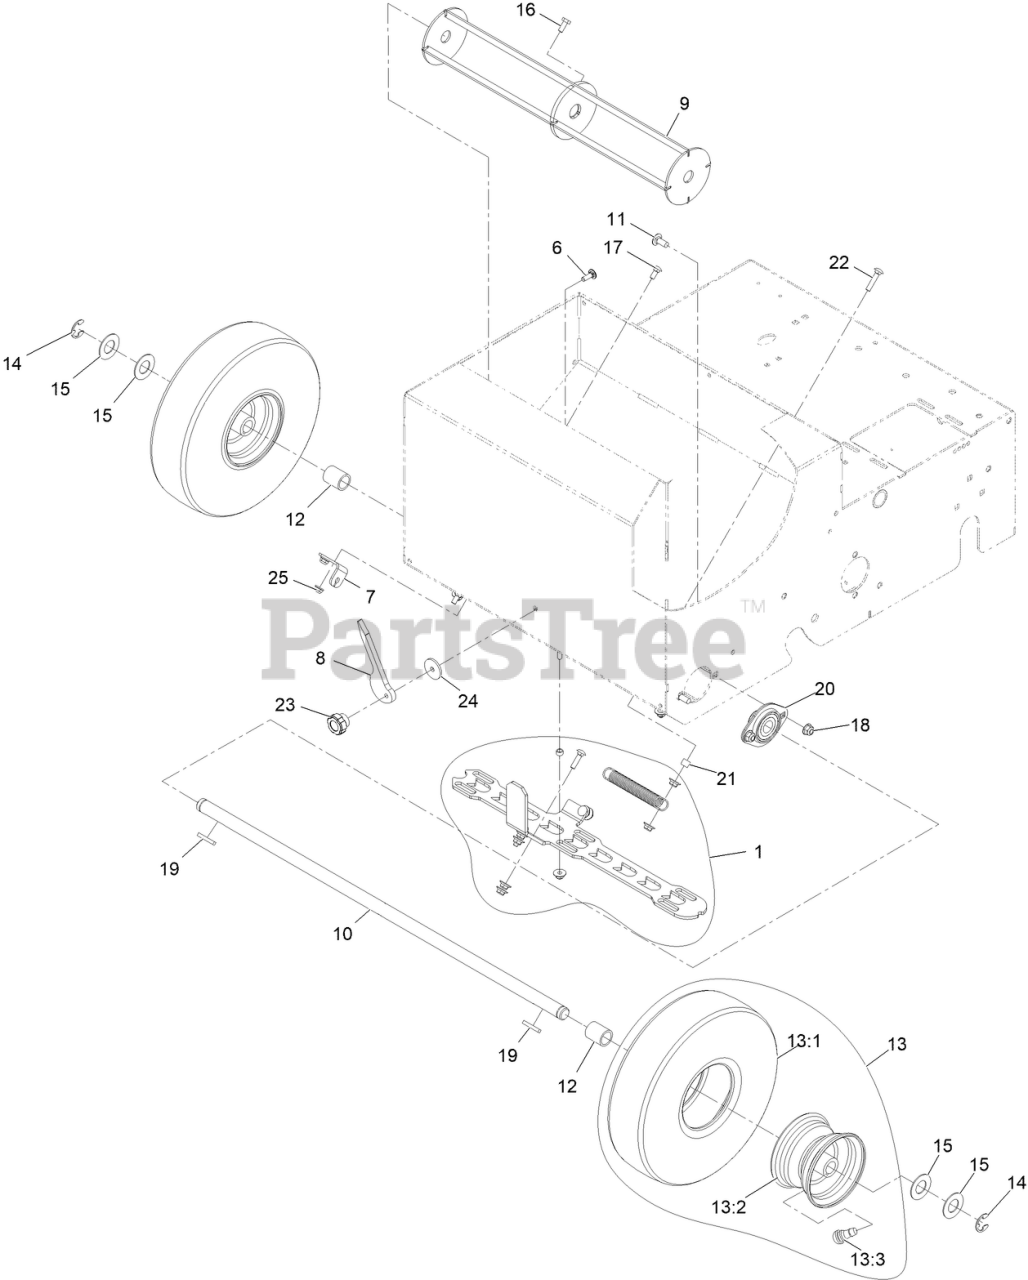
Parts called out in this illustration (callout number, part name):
1	SEED GATE KIT
6	BOLT-CARR
7	BRACKET-FLOW, SEED
8	GAUGE-FLOW, SEED
10	AXLE-FRONT
11	SCREW-CARR
13	WHEEL ASM
13:2	WHEEL-RIM
13:3	VALVE
15	WASHER-FLAT
16	SCREW-HH
17	SCREW-CARR
18	NUT-HF, NI
19	KEY-SQUARE
20	BEARING
22	SCREW-CARR
23	KNOB-CHUTE
24	WASHER
